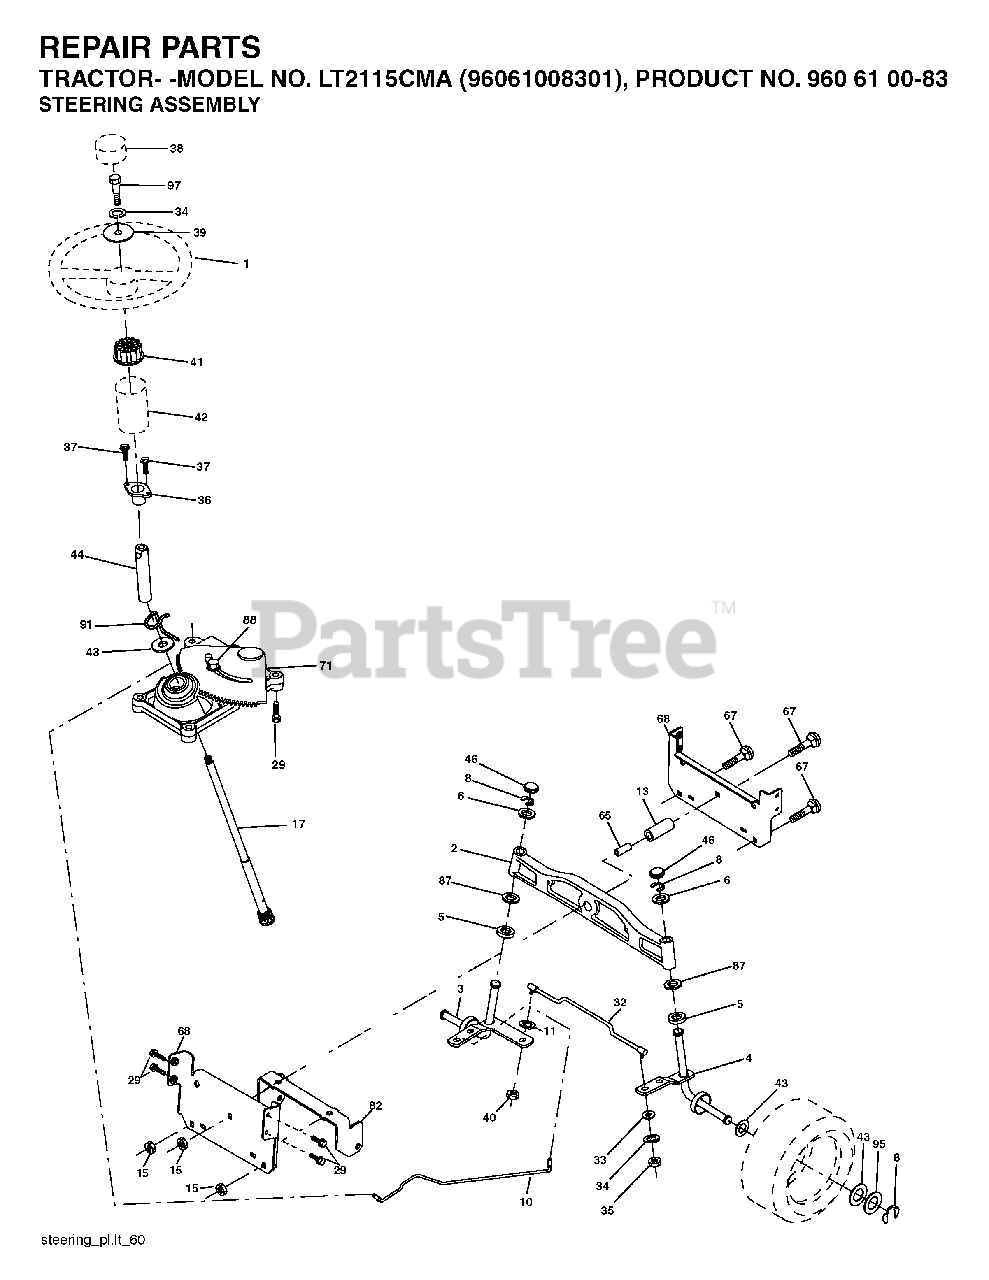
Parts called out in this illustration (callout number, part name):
1	WHEEL.STEERING.PREM.2.BLK
2	AXLE ASSY FRONT
3	SPINDLE.ASM.LH.15"TIRES
4	SPINDLE.ASM.RH.15"TIRES
8	RING CLIP
10	DRAGLINK.15".TIRES.2001
11	WASHER, LOCK 3/8
13	TUBE, PIVOT AXLE
15	NUT
17	SHAFT STEERING SPLINE
29	SCREW, 3/8-16X3/4
32	ROD.ASM.TIE.BALL.JOINT.NOVAN
33	WASHER M
34	LOCKWASHER
35	NUT, CROWNLOCK
36	BUSHING, STEERING
38	INSERT.CAP.STRG.WH.BLACK
39	WASHER.11/32
40	NUT CROWNLOCK 3/8-24
41	ADAPTER, WHEEL STNG..
42	BOOT.STEERING.SHAFT.BLACK
44	SHAFT.EXTEN.STRG.SPLINE
46	CAP.SPINDLE
65	SPACER BRACE AXLE
67	BOLT CARRIAGE
68	BRACE.AXLE.15"TIRES
71	STEERING ASM
82	BRACKET.SUSP.CHASSIS.FRONT.15
87	WASHER, FLAT .781 X 1 1/2"
88	BOLT, SHOULDER 7/16-20
91	CLIP.STEERING
95	WASHER.HARDENED
